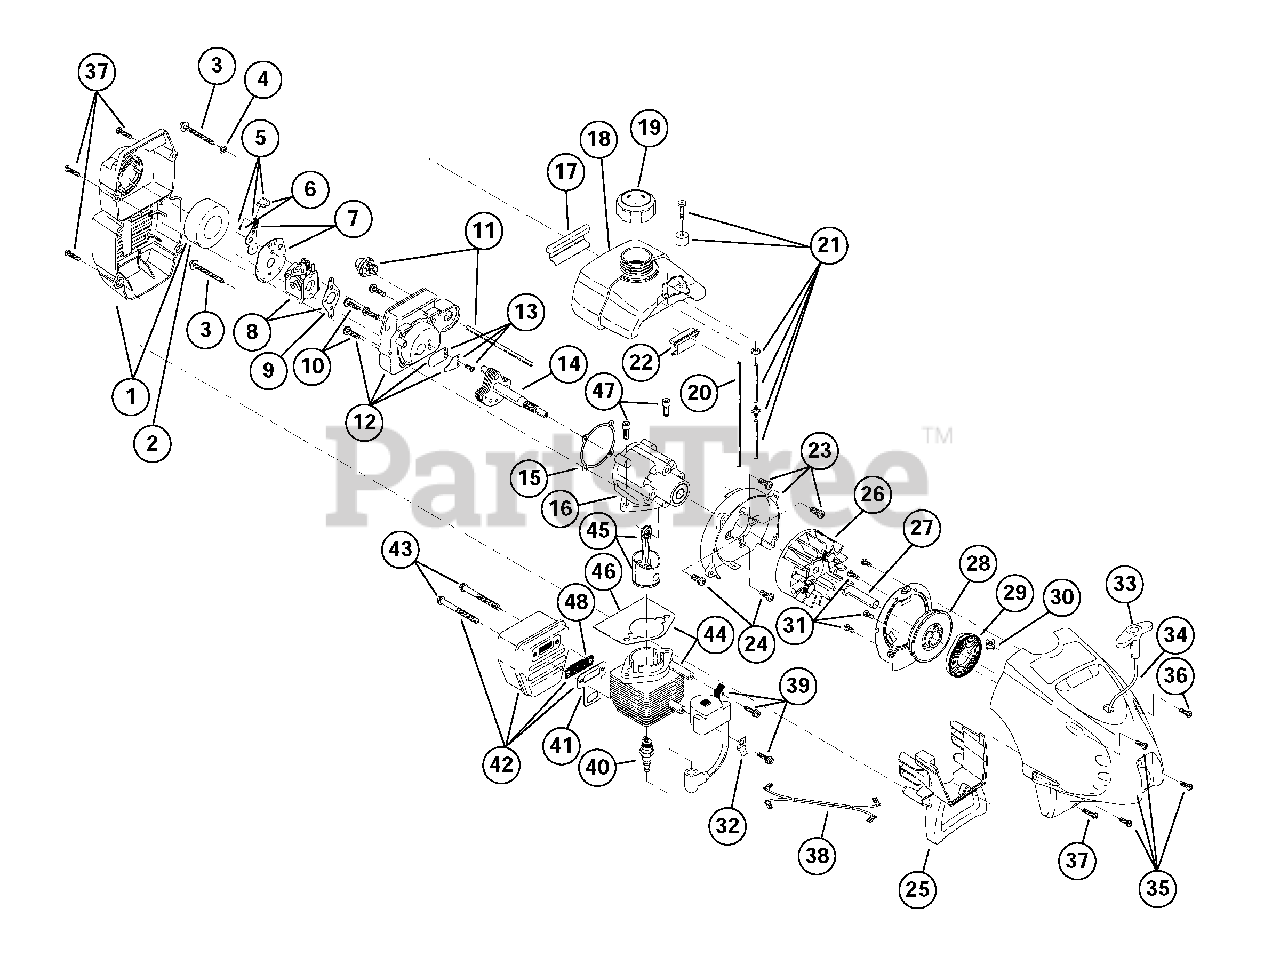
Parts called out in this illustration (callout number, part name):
1	Air Cleaner/Muffler Cover Assembly
2	Air Cleaner Filter
3	Carburetor Mounting Screw Assembly
4	Wavey Washer
5	Choke Lever Assembly
6	Choke Knob and Screw
7	Choke Lever and Plate
8	Carburetor Assembly
9	Carburetor Gasket
10	Carb Mount Screw
11	Primer and Hose Assembly
12	Carb Mount Assembly
13	Reed Assembly
14	Power Shaft Assembly
15	Rear Cover Gasket
16	Crankcase Service Assembly
17	Rear Mounting Pad
18	Fuel Tank Assembly
19	Fuel Cap Assembly
20	Fuel Return Line
21	Fuel Line Assembly
22	Front Mounting Pad
23	Shroud Assembly
24	Shroud Screw
25	Shroud Extension and Stand
26	Flywheel Assembly
27	Nut, Square Drive
28	Recoil Pulley Assembly
29	Recoil Spring
30	Rope Guide
31	Pulley Retainer Assembly
32	Ground Tab
33	Pull Handle
35	Starter Housing Assembly
36	Housing Screw
37	Cover Screw
38	Wire Lead
39	Module Assembly
40	Spark Plug
41	Exhaust Gasket
42	Muffler Assembly
43	Muffler Mounting Bolt Assembly
44	Cylinder Assembly
45	Piston and Rod Assembly
46	Cylinder Gasket
47	Cylinder Bolt
48	Spark Arrestor Screen
